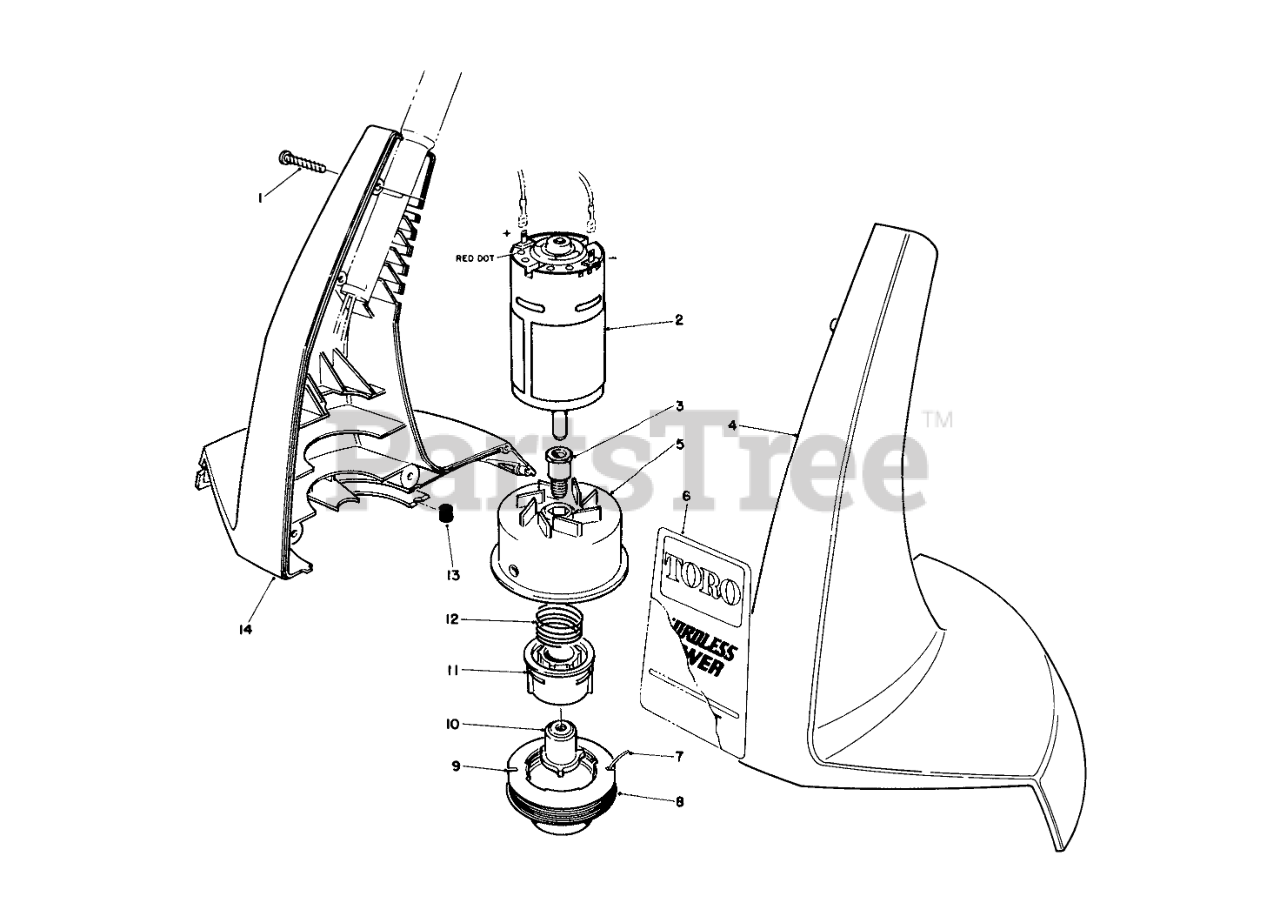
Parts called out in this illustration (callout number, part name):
1	Screw
2	Motor Assembly (Incl. Ref. #3)
3	Extension-Shaft
4	LH HOUSING, 12V TRIMMER
5	Drum-Assembly
6	DECAL-TRIMMER
8	Pre-wound Spool (Incl. Ref. #7 & 9)
9	CAP-SPOOL
10	DRIVER
11	CORE - SPOOL
12	Spring
13	GROMMET
14	RIGHT HAND HOUSING ASM
